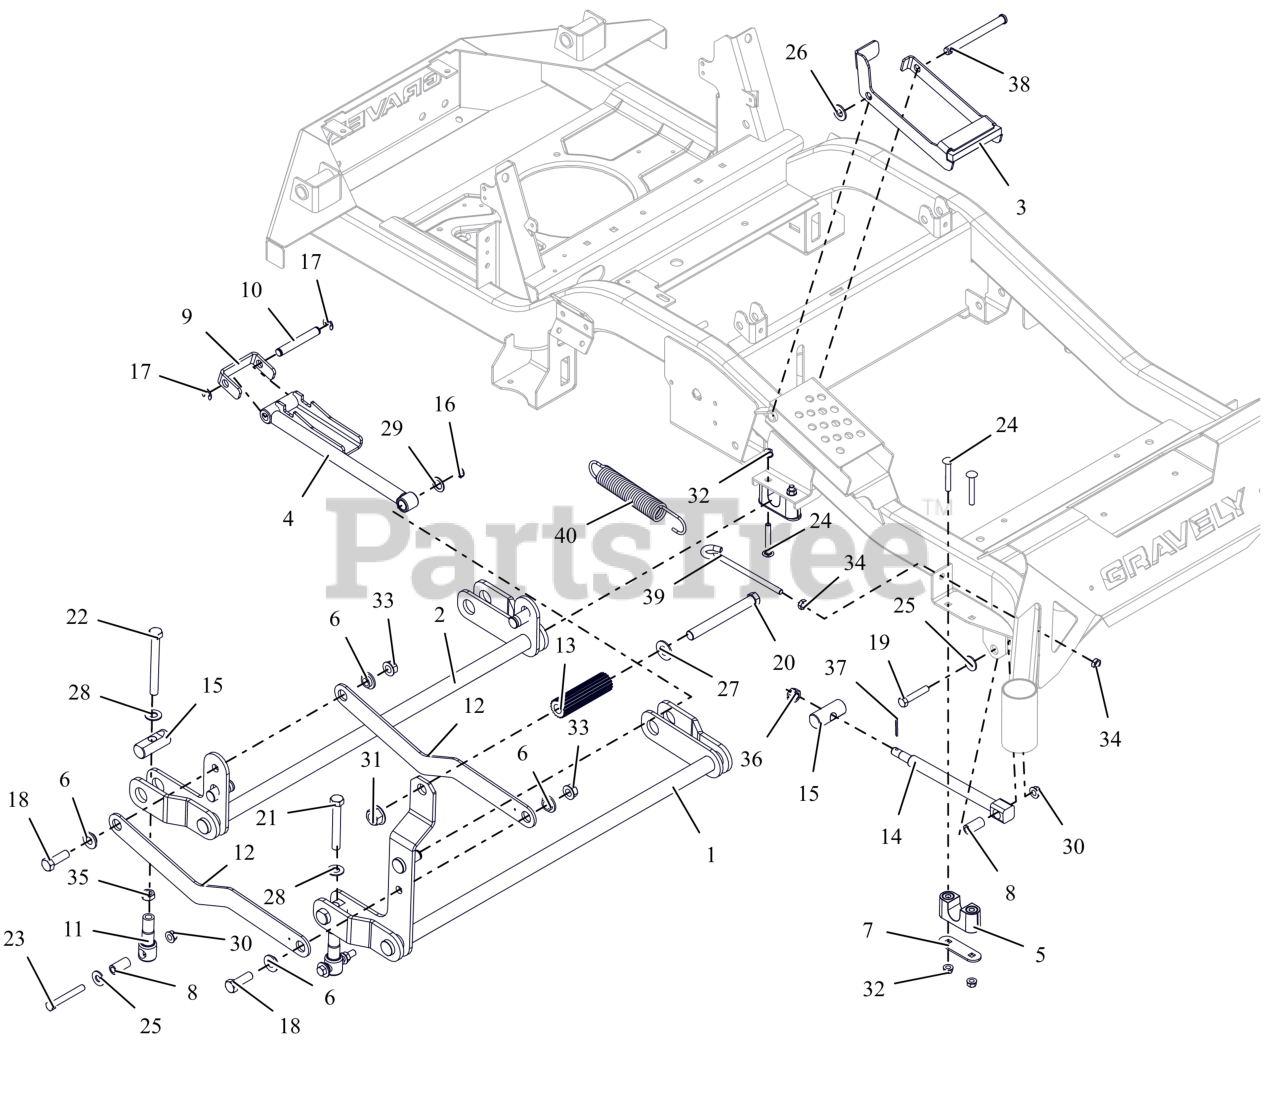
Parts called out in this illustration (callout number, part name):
1	WLDMT, FRONT DECK LIFT PIVOT
2	WLDMT, REAR DECK LIFT PIVOT
3	WLDMT, HOC TRANSFER LOCK (BLACK)
4	WLDMT, HOC LIFT ARM (BLACK)
5	ASM-BUSHING, DECK LIFT
6	BSHG-FLG .515X.750X.310X1.120
7	PLATE, BEARING SUPPORT
8	SPACER, DECK LEVELING
9	BRKT, HOC LINE
10	ROD, HOC PIVOT
11	LINK, DECK LIFT FORMED
12	LINK, DECK
13	ROD, FOOT PEDAL (BLACK)
14	DRAG,LINK-HD
15	PIN, DECK LIFT
16	RG-RTNG-EXT .625X.050
17	RG-RTNG-EXT .500X.042 (E)
18	BLT,HEX .50-13X1.50 G5 ZCC
19	BLT,HEX .38-16X2.00 G5 ZCC
20	BLT, HEX .62-11X5.50 G5 FBP
21	BLT, HEX 0.5-13X3.5F GR5 ZCC
22	BLT, HEX .50-13X4.50F G8 ZCC
23	BLT, HEX .38-16X2.75 G8 ZCC
24	BLT, RHSSN.31-18X2.25 G5 ZCC
25	WSHR,FLT .438X1.00X.083 ZCC
26	WSHR,FLT .531X1.062X.095 ZCC
27	WSHRFLT 5/8SAE CARBHARD FBP
28	WSHR, FLT .557X1.040X.102 ZCC
29	WSHR, FLT .630X1.005X.062 ZCC
30	NUT-LK-TOP-FLG .38-16 ZC120
31	NUT,FLG-TOP LK .625-11 FBP
32	NUT,LK-CTR-FLG .31-18 GF ZCC
33	NUT-LK-TOP-FLG .500-13 GF ZCC
34	NUT-JAM .375-16 G2 ZCC
35	NUT-JAM .500-13 G2 ZCC
36	NUT-SL .50-13
37	PIN,CTR.12X1.25EXTPRSQCT ZC120
38	PIN, SLIC-.500X4.97X4.55 -ZC
39	BOLT,.38-16 X 5.25-.62 DIA EYE
40	SG-TENS .162X1.25X8.25 WLD 25
